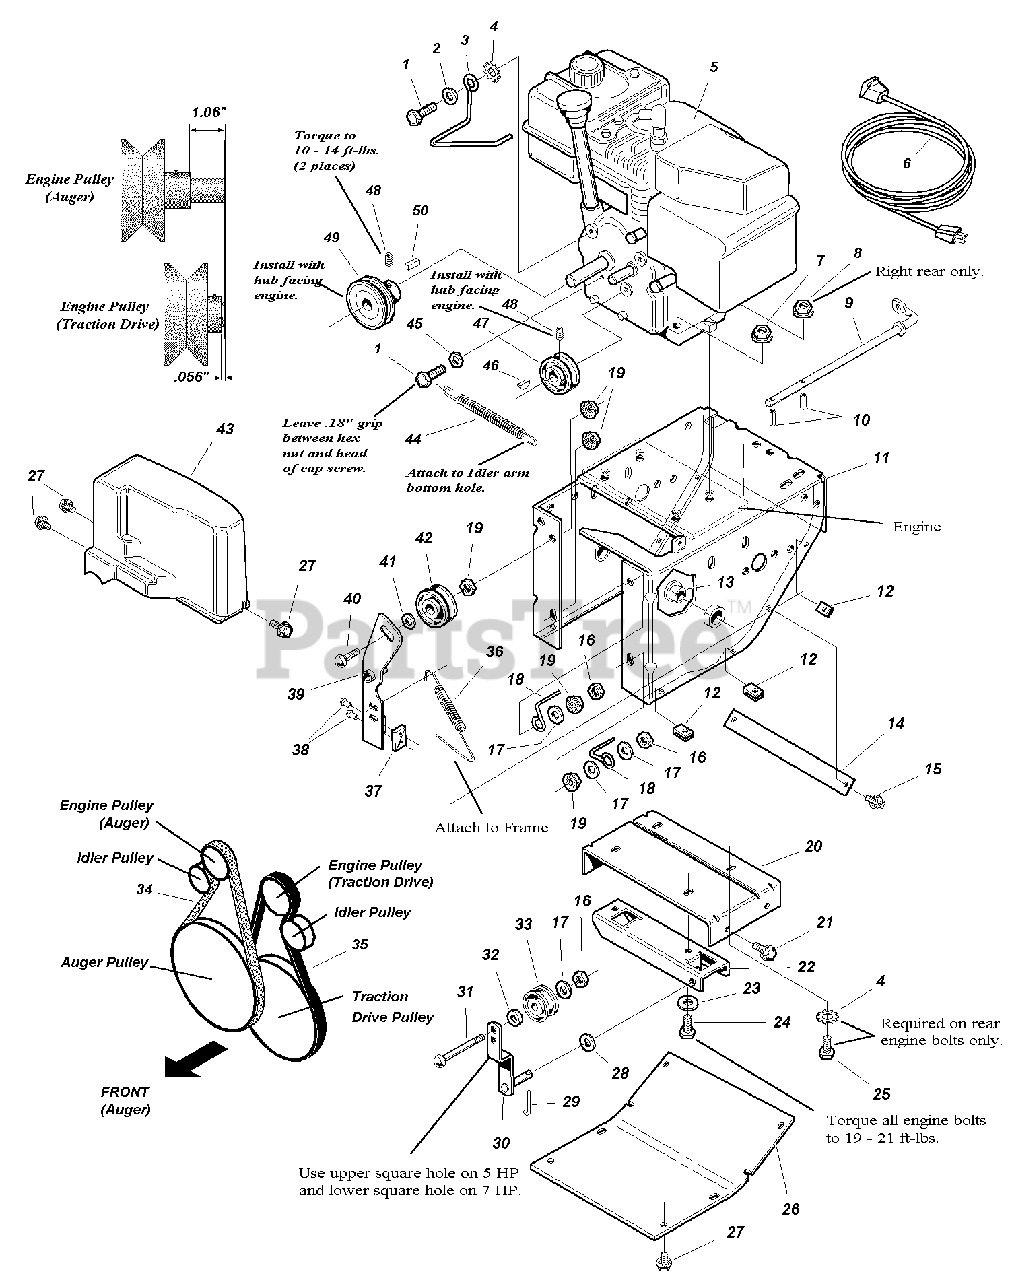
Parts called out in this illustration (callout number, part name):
1	CAPSCREW, Hex Hd., 5/16-24 x 3/4
2	WASHER, 5/16
4	LOCKWASHER, External Tooth, 3/8
7	NUT, Hex, Flange Whizlock, 5/16-18
8	NUT, Hex Flange Whiz Lock, 5/16-18
10	PIN, Spring
12	NUT, Speed 1/4-20
14	TIE BAR SUPPORT
15	CAPSCREW, Taptite, #10-24 x 1/2
16	NUT, Hex, Jam, Center-lock, 3/8-16
17	WASHER, Flat
18	GUIDE, Belt
19	NUT, Hex, Flange, Locking, 3/8-16
20	FRAME BRACKET
21	CAPSCREW, Taptite, 5/16-18 X 1/2
22	SUPPORT, Pivot
23	WASHER
24	CAPSCREW, Hex Hd., 5/16-18 x 1-3/4
25	CAPSCREW, Hex Head, 5/16-18 x 1 3/4 G5
26	COVER, Bottom
27	CAPSCREW, Taptite, 1/4-20 x 1/2
28	WASHER, Flat 15/32
29	PIN, Cotter
30	ARM & SHAFT ASSEMBLY, Idler
31	CARRIAGE BOLT, 3/8-16 X 1-1/4
33	PULLEY, Idler - Traction Drive
34	V-BELT, 4L, Auger Drive
35	V-BELT, 3L Traction Drive, (1693980 & 1693981)
35	V-BELT, 3L Traction Drive (1693982 & 1693983)
36	SPRING, Extension
39	ARM & HUB ASSEMBLY, Idler/Brake (Includes Ref. 37 and 38)
40	CARRIAGE BOLT, 3/8-16 x 1-3/4
41	WASHER, 3/8
42	PULLEY, Idler - Auger Drive
43	COVER, Belt, (1693980 & 1693981)
43	COVER, Belt, (1693982 & 1693983)
44	SPRING, Extension
45	NUT, Hex, Jam, 5/16-24
46	KEY, Hi-Pro, 1/8 x 5/8
47	PULLEY, Engine - Traction Drive
48	SET SCREW, Hex Socket Cup Point, 5/16-18 x 5/16
49	PULLEY, Engine - Auger Drive
50	KEY, Parallel, 3/16 x 3/16
